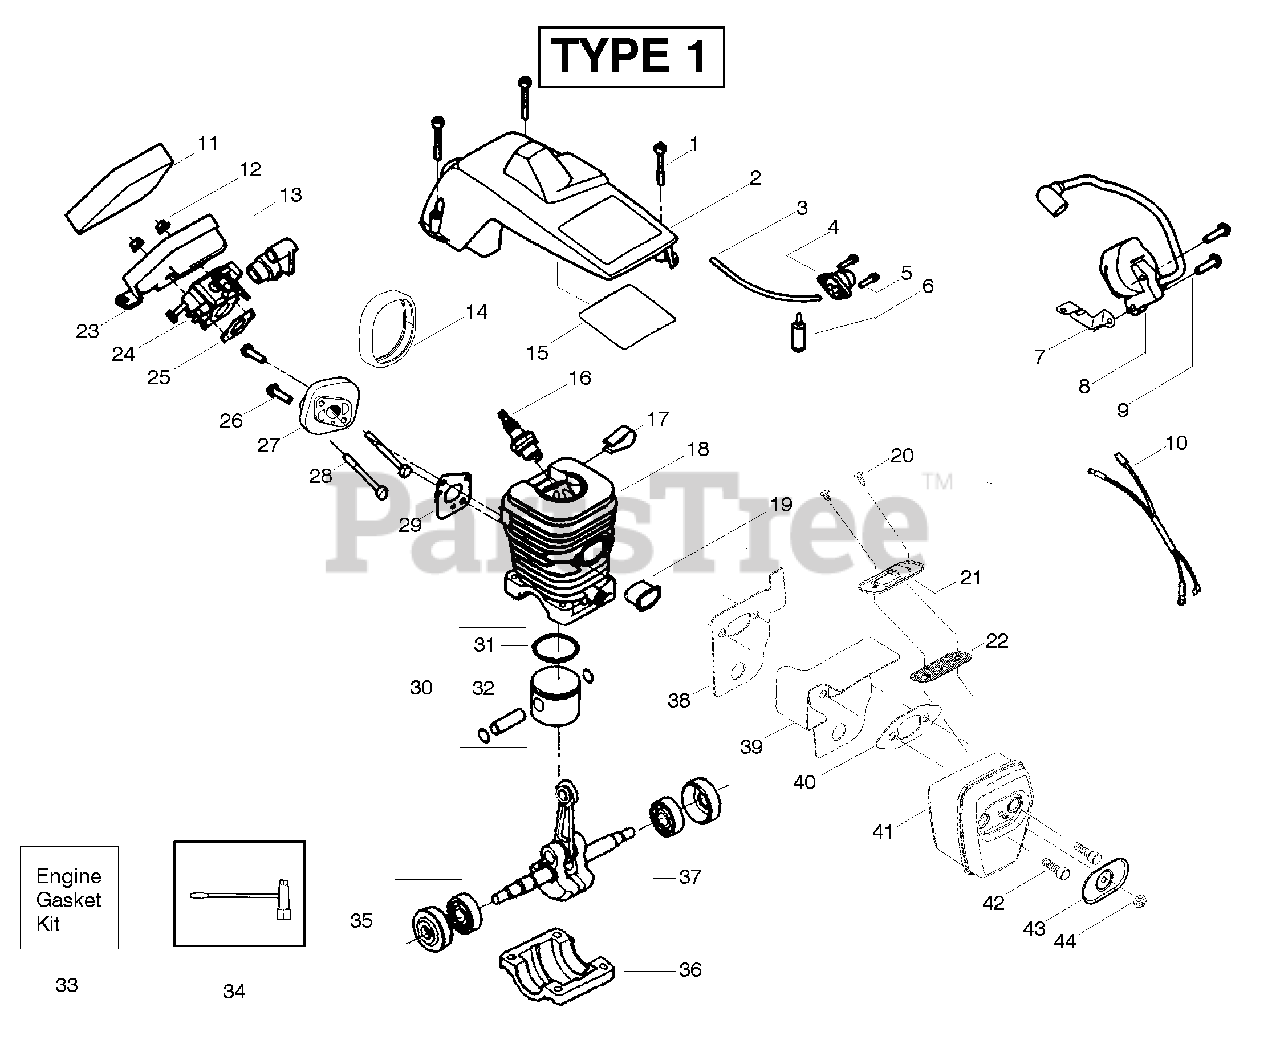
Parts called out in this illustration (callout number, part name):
2	Assy-Cylinder Shield
3	Kit-Fuel Line (Small)
4	Assy- Air Purge
6	Assy-Fuel Pick-up
7	Strap-Ground
8	Ignition Module
10	Assy-Wire Harness
11	Foam- Air Filter
13	Grommet-Carb Adjust
14	Seal-Carb Adapter
15	Reflector-Heat
16	Spark Plug (RCJ-7Y)
17	Clip-High Tension Lead
18	Kit-Cylinder
19	Insulator-Heat
20	Screw-Outlet cover
21	Cover - Outlet
22	Kit-Spark Arrestor
23	Air Filter Housing
24	Kit-Carburetor, (WT-599)
24	Kit-Carburetor, (W-9A)
25	Gasket-Carb.
27	Carb. Adapter
29	Gasket-Carb Adaptor
30	Kit-Piston
31	Ring-Piston
32	Retainer-Piston Pin
33	Kit-Engine Gasket
34	Bar Wrench
35	Assy-Seal & Bearing
36	Cap-Crankcase
37	Assy-Crankshaft
38	Backplate
39	Guide-Outlet
40	Gasket-Muffler
41	Assy-Muffler
42	Bolt-Muffler
43	Cover-Bolt
44	Nut-Brass
